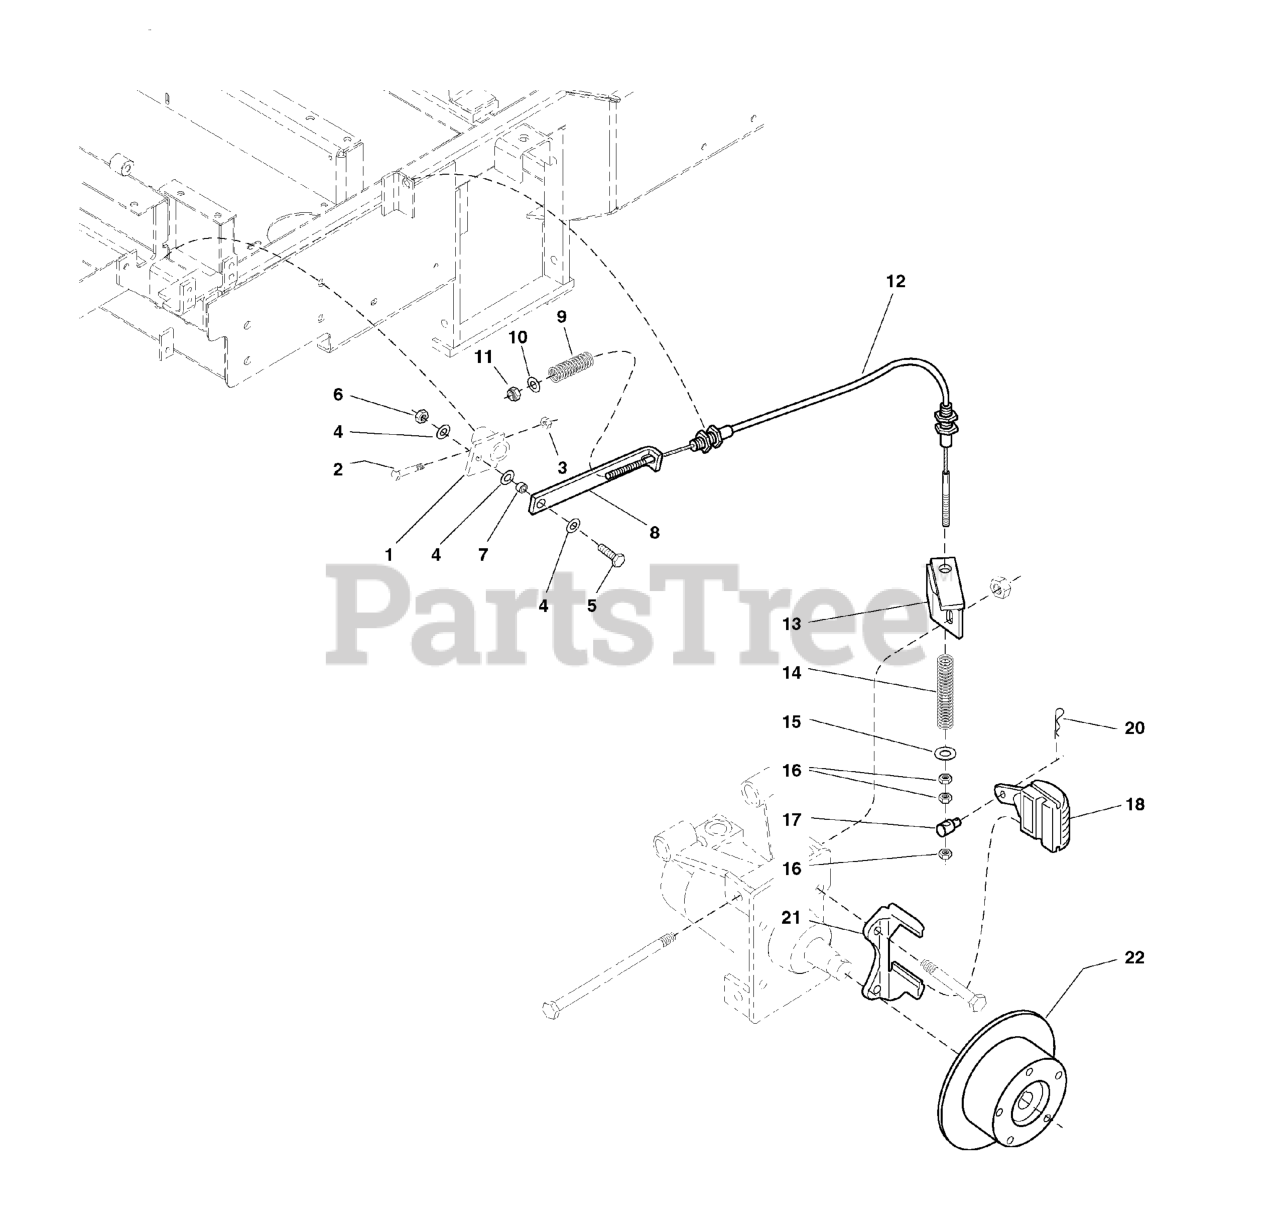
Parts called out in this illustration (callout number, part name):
1	BRAKE LINKAGE PIVOT
4	WASHER, 3/8 SAE
5	BOLT, 3/8-16 X 1" GD5 CZ
6	NUT, 3/8-16 Hex Side Lock
7	SPACER, .38 x .50 x .27
8	LINK, Brake Lock
9	SPRING, Compression
10	WASHER, 5/16" SAE
11	NUT, 5/16-24 HEX NYLON LOCK
12	CABLE, Brake
13	BRACKET, Cable Mount-LH
14	SPRING, Compression
15	WASHER, 5/16" Fender
16	NUT, 5/16-24 Hex
17	ADJUSTER, Brake Linkage
18	BRAKE CALIPER, LH
19	BRAKE PAD KIT
20	HAIRPIN CLIP
21	MOUNT, Brake Caliper
22	HUB, 8" Brake Disc
